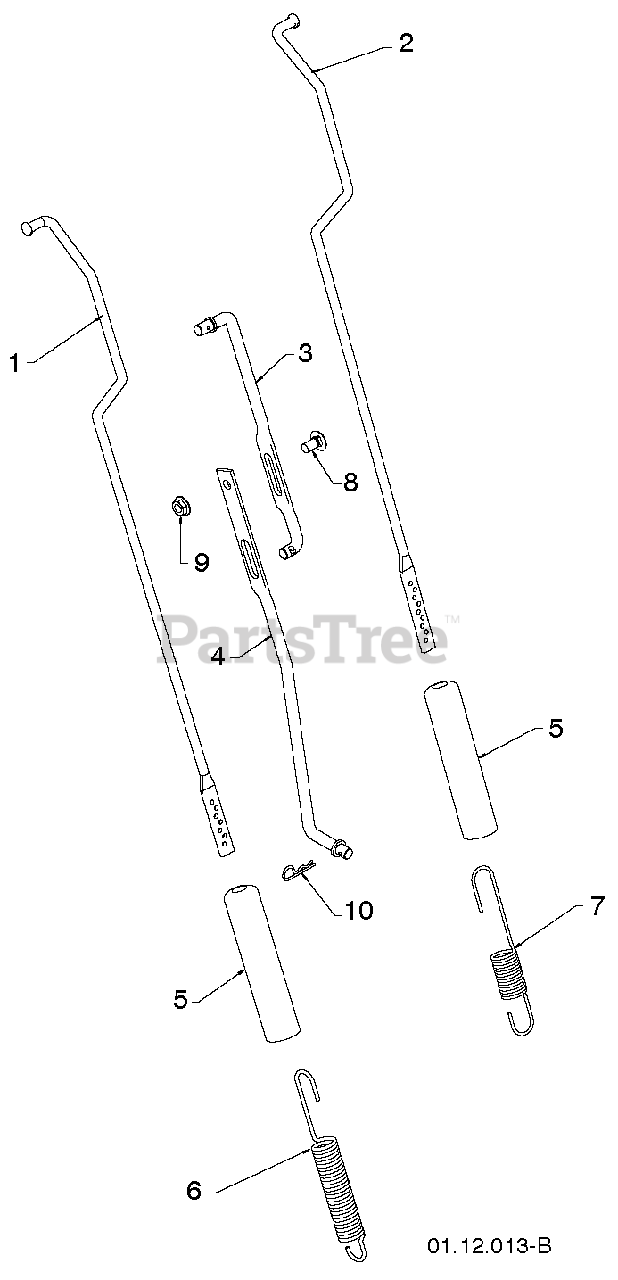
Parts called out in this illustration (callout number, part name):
1	ROD.IMPELLER
2	ROD.TRACTION
3	ROD, UPPER SPEED CONTROL
4	ROD, LOWER SPEED CONTROL.SNOW
5	SLEEVE, SPRING
6	SPRING.CONTROL.ROD.SNOW
7	SPRING.TRACTION.ROD.SNOW
8	BOLT
9	NUT.FLANGE.5/16
10	SPRING RETAINER
